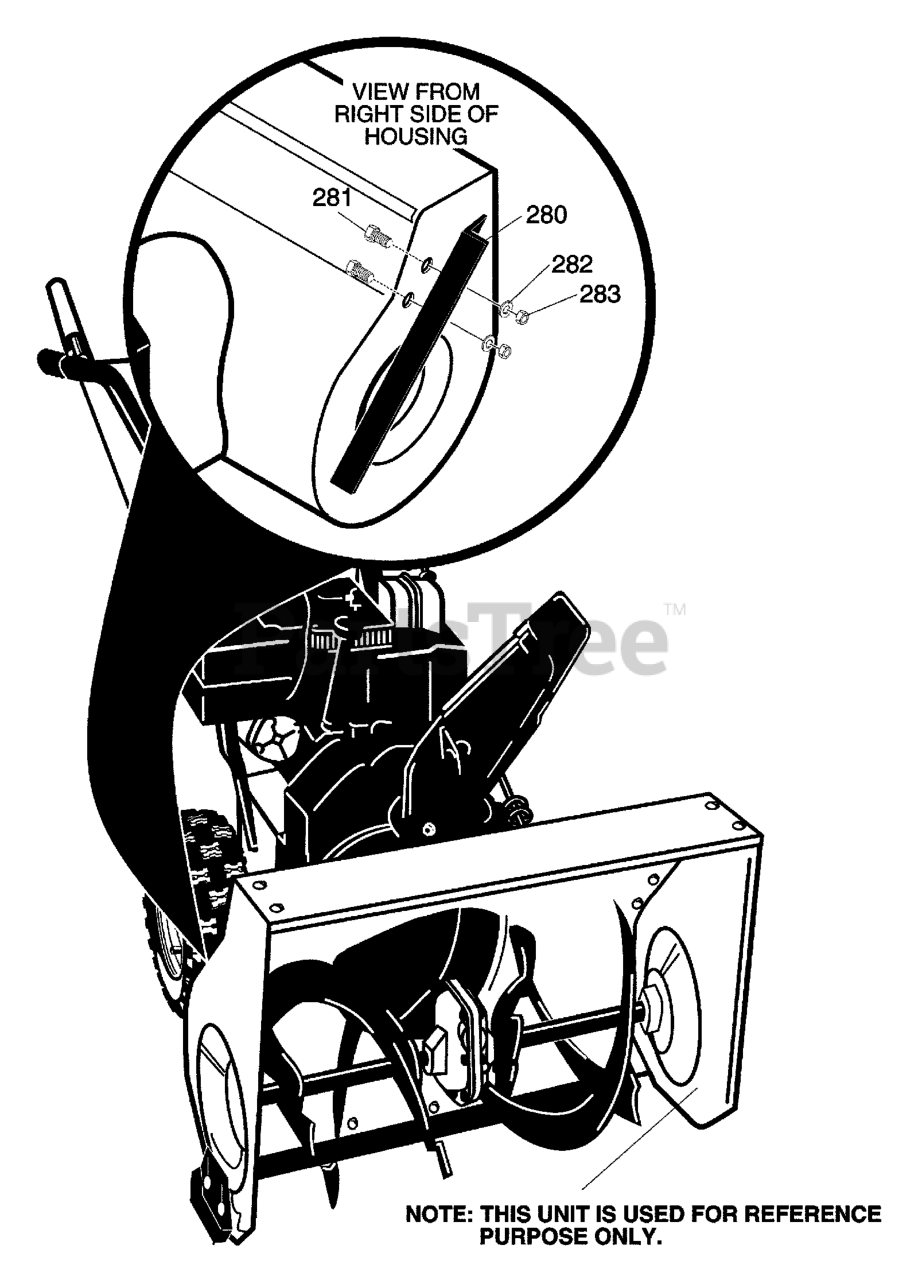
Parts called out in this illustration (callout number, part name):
280	BAR, DRIFT CUTTER
281	BOLT, 5/16-18X0.75
282	WASHER, SPLIT
283	NUT, 5/16-18
